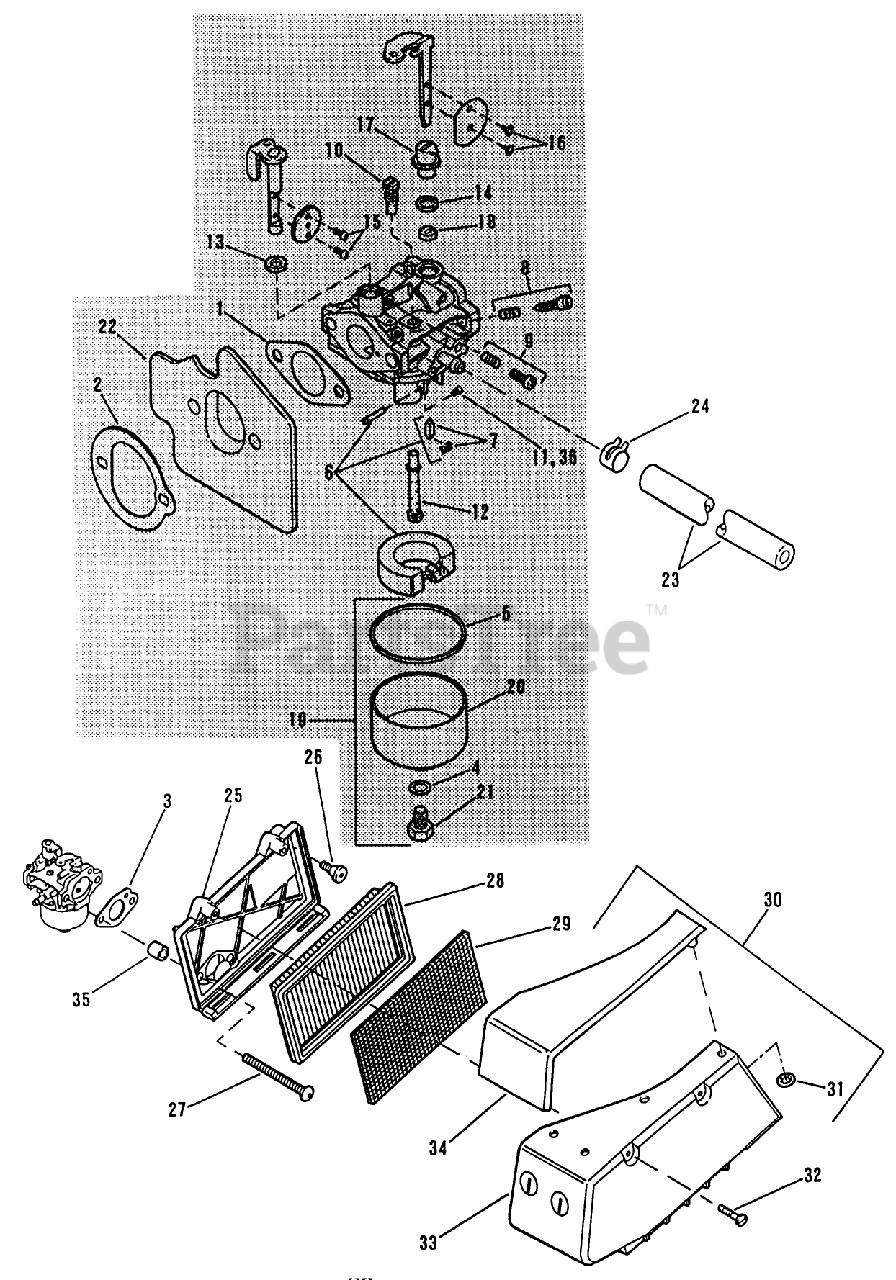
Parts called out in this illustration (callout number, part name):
1	GASKET SM
2	GASKET SM
3	GASKET-FIL SM
4	GASKET-BOWL RET S
5	GASKET-FUELBOWL S
7	NEEDLE & CLIP S
10	PILOT JET
11	CARB JET
14	SEAL CHOKE SHAFT
16	SCREW CHOKE VALVE
21	SCREW,BOWL RET S
22	SPACER & NOZZ SM
23	GAS LINE SM
24	HOSE CLAMP SM
28	ELEMENT-AIR SM
31	NUT-PUSH
36	MAIN JET
